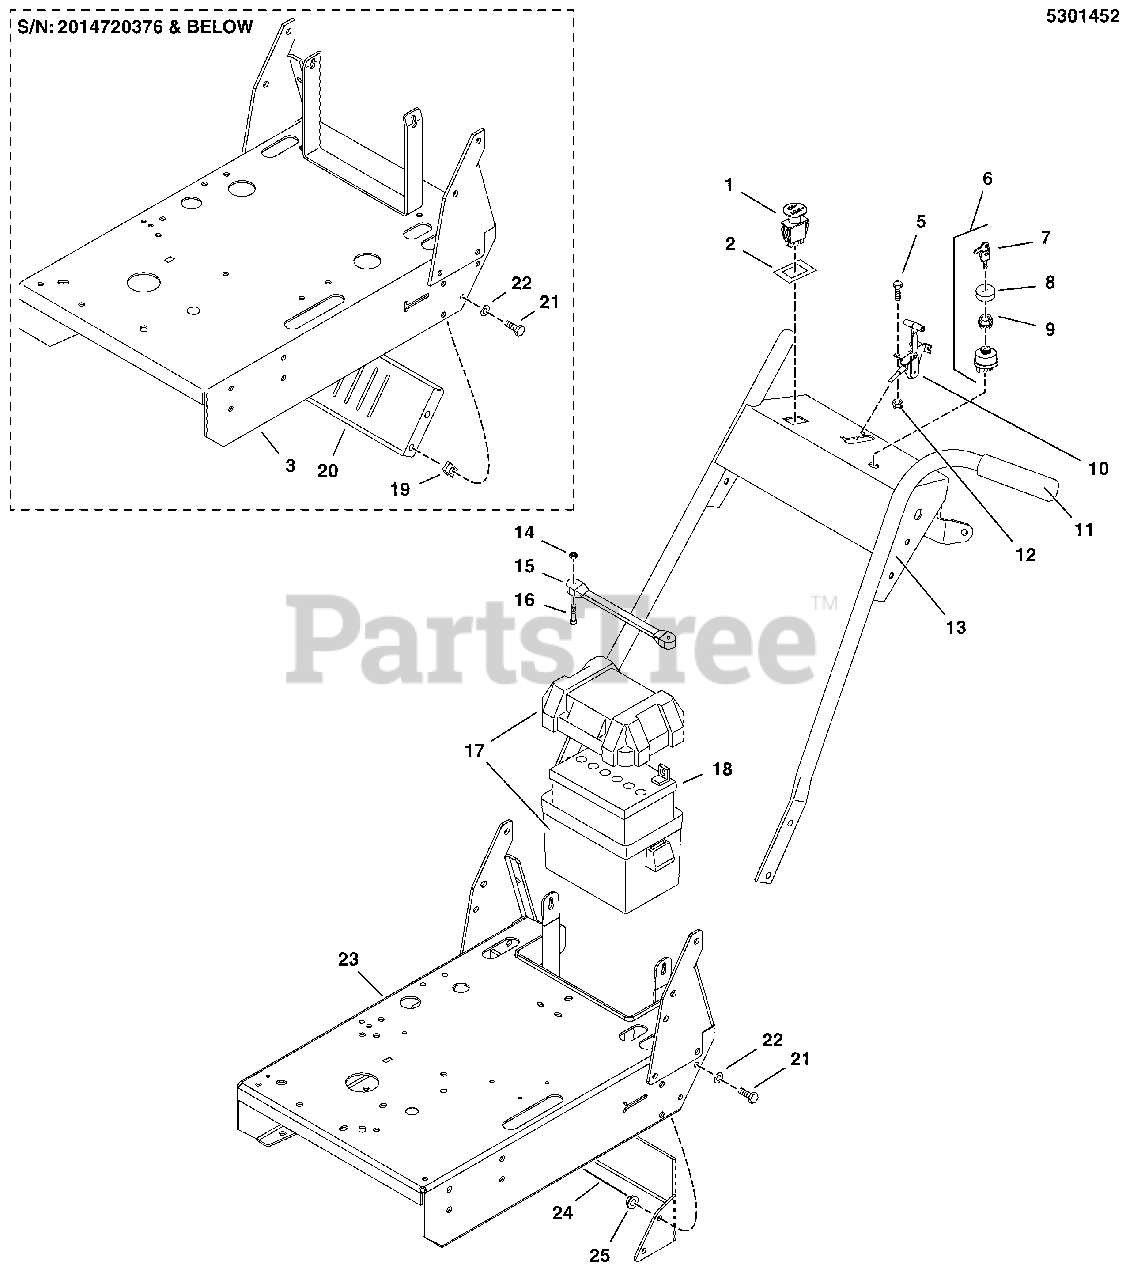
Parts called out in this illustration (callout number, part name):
1	SWITCH, BLADE ENGAGEMENT
2	RING, SWITCH RETAINER
3	WELD, ENGINE DECK, HC36 - ORG
6	SWITCH, IGNITION, 6 POST
7	KEY, IGNITION, MOLDED SET
8	COVER, PLASTIC SNAP ON
9	NUT, PLASTIC
10	CABLE, THROTTLE CONTROL, 48"
10	CABLE, THROTTLE CONTROL, 40"
11	GRIP, FOAM, .940 X 5 X .187
12	NUT, 1/4-20 HEX NYLOCK FLANGE (5025391)
13	WELD, HANDLE BAR
14	NUT, #10-24 HEX NYLON LOCK
15	STRAP, RUBBER
16	SCREW, #10-24 X 1 RS, CZ
17	BATTERY BOX, W/ DRAIN HOLE
18	BATTERY, WET ( BCIU1, 340 CCA)
19	CLIP, BODY , 5/16-18 FOR 7 GA.
20	SHIELD, REAR
21	BOLT, 5/16-18 X 1 GD5 YZ
22	WASHER, 5/16 SAE
23	WELD, ENGINE DECK, HYDROCUT - ORG
24	PLATE, BUMPER, HYDROCUT - ORG
25	NUT, 5/16-18 HEX NYLOCK FLANGE
